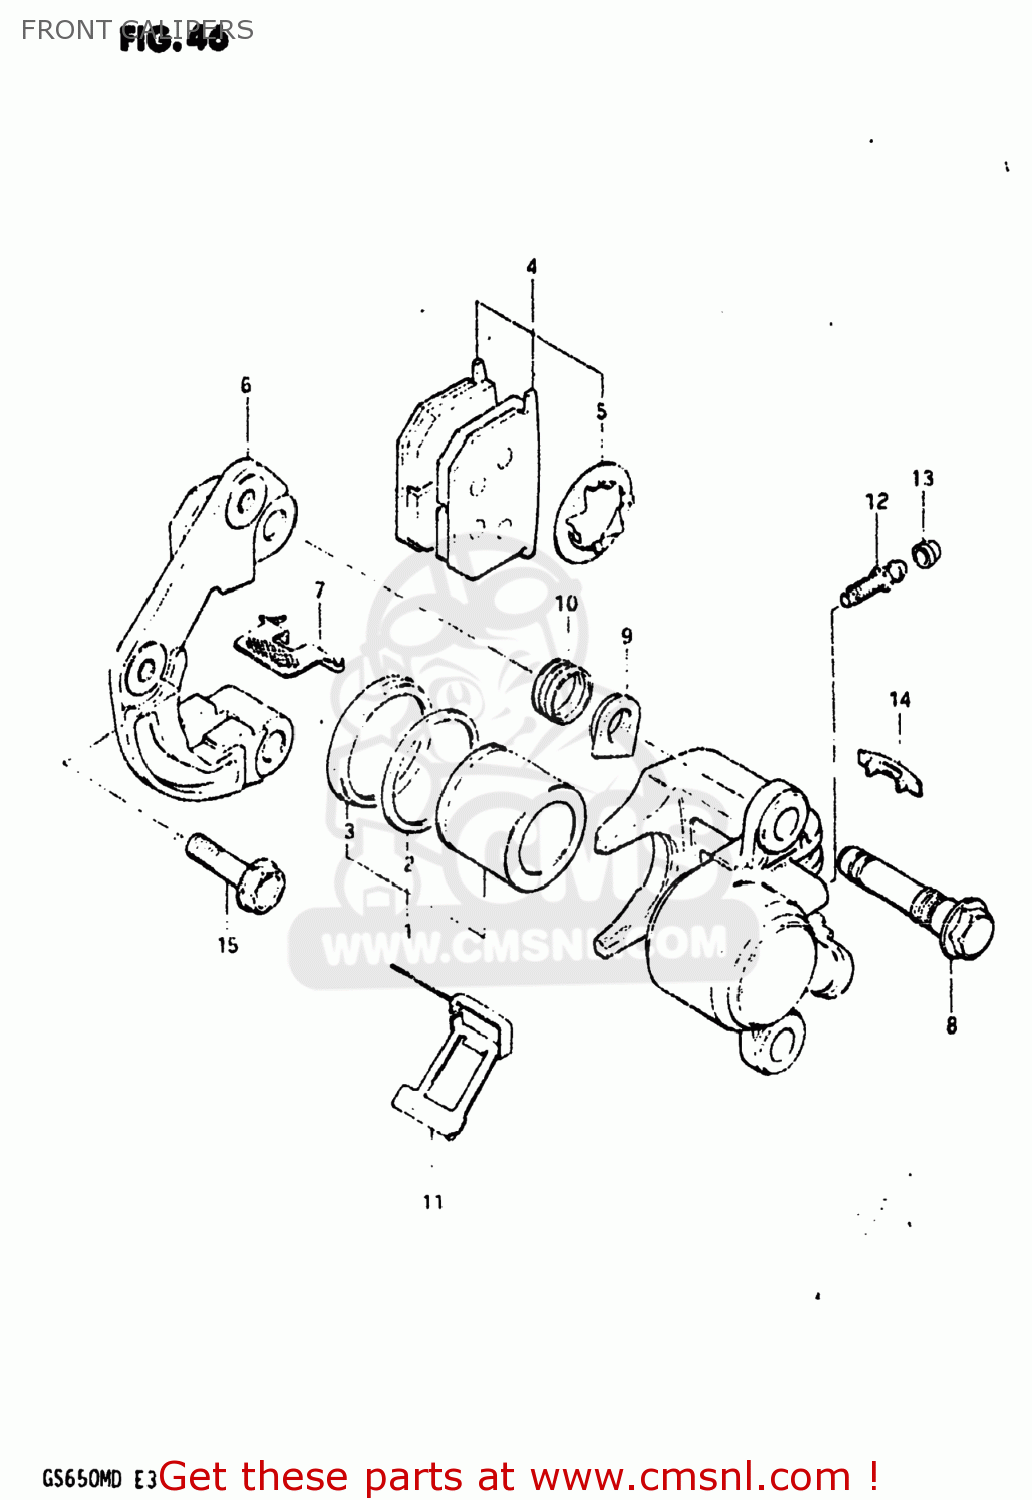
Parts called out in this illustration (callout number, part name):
0	CALIPER ASSEMBLY,FRONT,LEFT
1	PISTON SET
2	SEAL,PISTON
3	BOOT,PISTON
4	PAD & SHIM SET (MCA)
5	SHIM,PAD
6	HOLDER,CALIPER,LEFT
7	PAD,GUIDE
8	AXLE,CALIPER
9	NUT,CALIPER AXLE
10	BOOT
11	SPRING
12	BREATHER
13	CAP,BLEEDER PL
14	COVER,INDICATOR
15	BOLT 10X37
